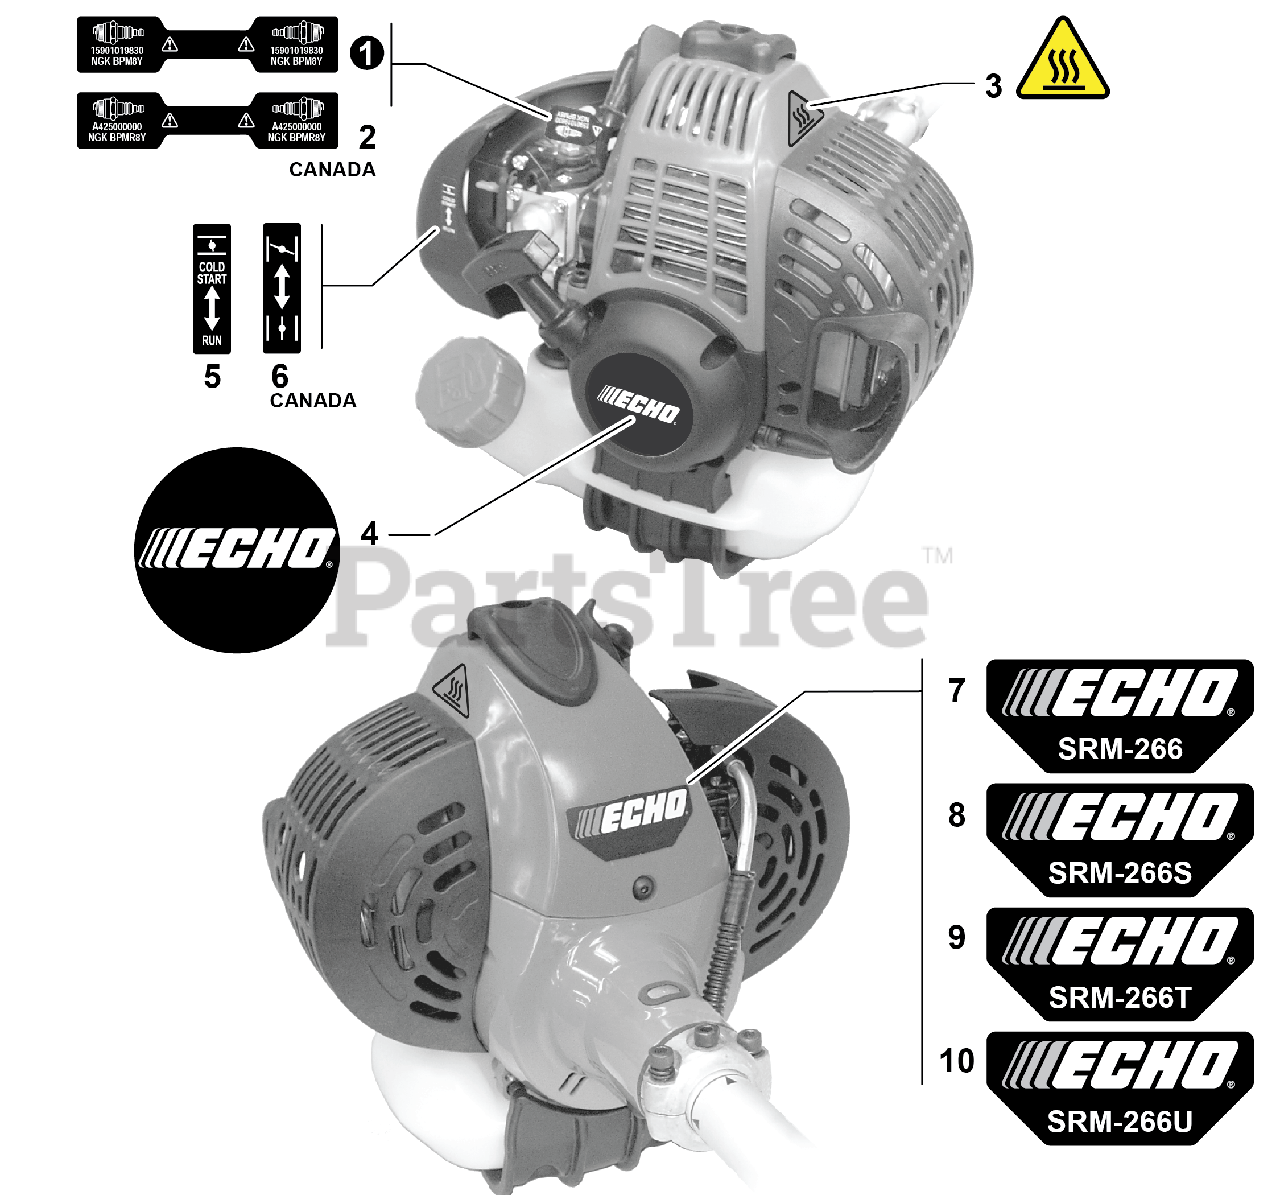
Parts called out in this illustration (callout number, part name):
1	LABEL, SPARK PLUG - BPM8Y
2	LABEL, SPARK PLUG - BPMR8Y
3	LABEL, CAUTION - HOT
4	LABEL, RECOIL STARTER
5	LABEL, CHOKE
6	LABEL, CHOKE
7	LABEL - MODEL SRM-266
8	LABEL - MODEL SRM-266S
9	LABEL - MODEL SRM-266T
10	LABEL - MODEL SRM-266U
